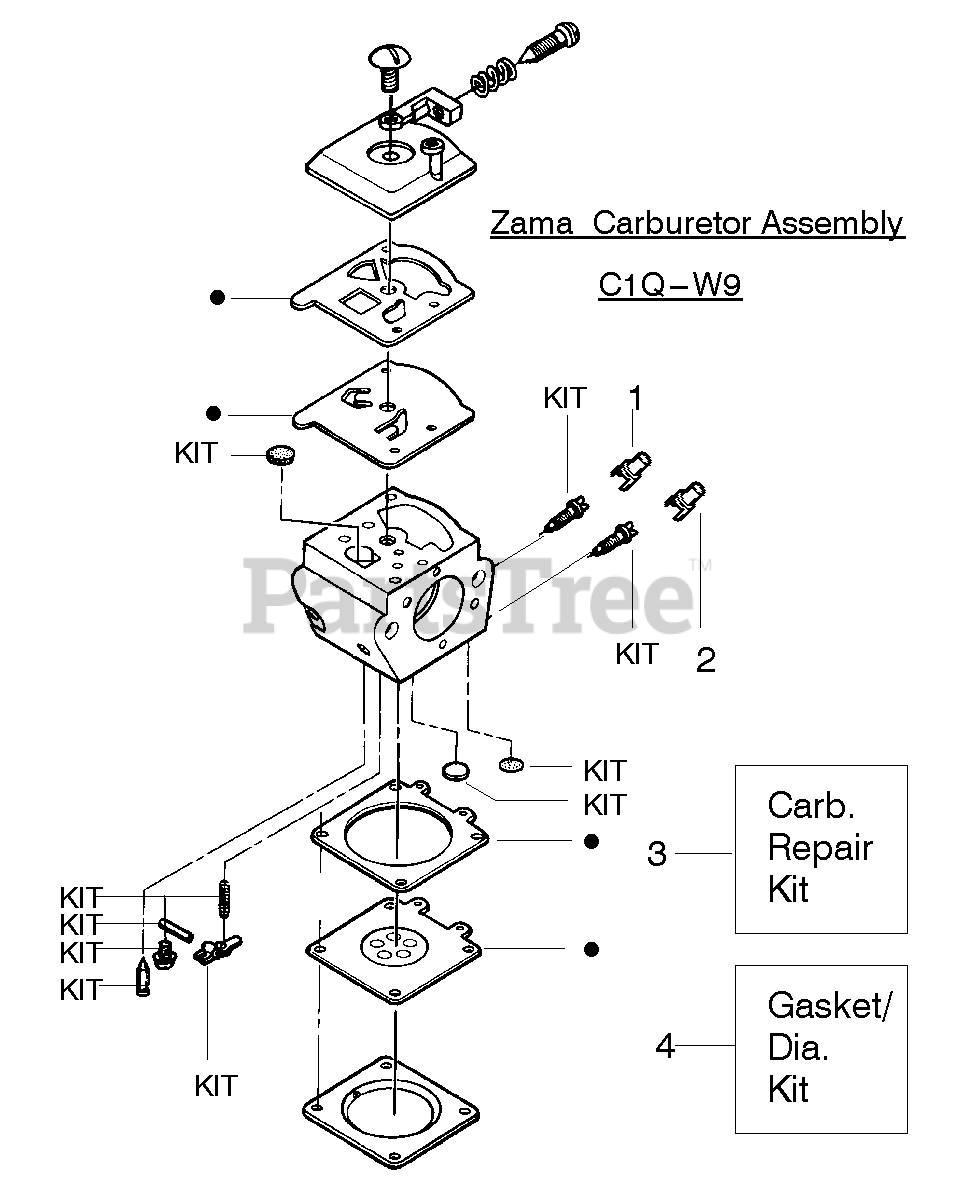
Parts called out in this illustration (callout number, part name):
1	Limiter Cap-High (brown)
2	Limiter Cap-Low (tan)
3	Carburetor Repair Kit Zama (GND-27)
4	Gasket Diaphragm Kit Zama (KSO31173)
